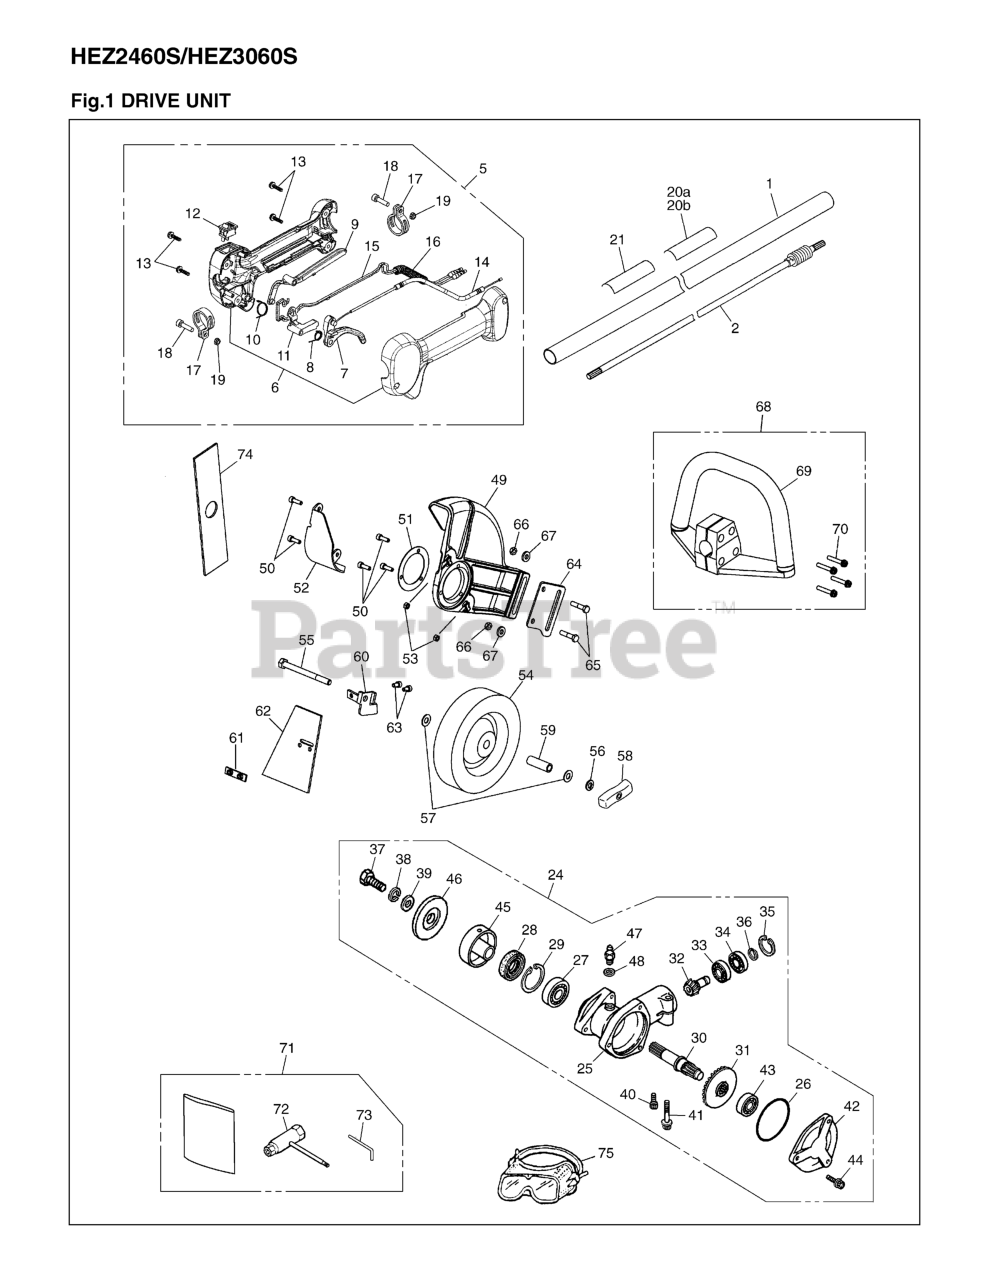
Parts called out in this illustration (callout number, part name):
1	PIPE COMP
5	GRIP ASSY
6	GRIP, HALF SET
7	LEVER, THROTTLE
8	SPRING, THROTTLE
9	LEVER FOR GRIP (
11	LEVER JOINT
15	CORD - C
18	BOLT (RPLS 28501
19	NUT
20B	LABEL NAME
21	LABEL CAUTON FOR
24	GEARCASE
25	GEARCASE
26	O-RING
28	SEAL, OIL
30	SHAFT, GEAR (-13
32	PINION
33	BEARING (RPLS T3
35	RING, SNAP, M24
36	RING, SNAP (RPLS
37	BOLT, LH
38	WASHER (RPLS 318
39	WASHER,M8x2.3(RP
40	BOLT, M5 x 12
41	BOLT, M6 x 1.35
42	COVER
43	BEARING (RPLS 06
45	HOLDER (A)(RPLS
46	HOLDER (B)
47	FITTING, GREASE
48	WASHER, M6 x .8
49	Guard
50	BOLT (M5x0.8-16)
52	PROTECTOR
53	NUT, M5 x 4
54	WHEEL (RPLS T305
55	BOLT
56	WASHER, SPRING(T
57	WASHER
62	RUBBER (FLAP)
63	BOLT, M5 x 10
64	MAIN BRACKET
65	BOLT
67	WASHER
68	HANDLE ASSY. (RP
69	HANDLE T
71	Tool-Set
73	BAR
74	BLADE, EDGER (RP
75	GOGGLExxx (RPLS
